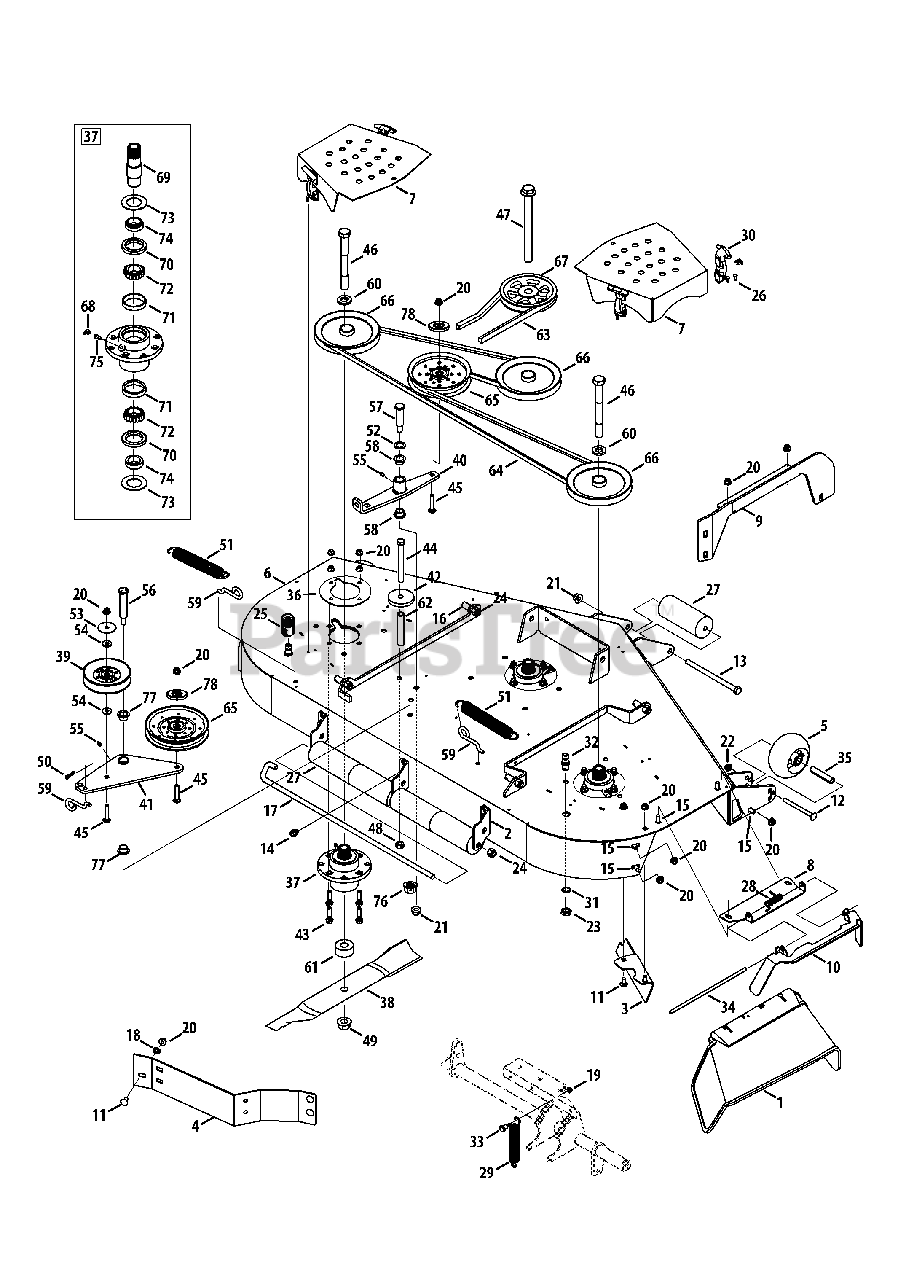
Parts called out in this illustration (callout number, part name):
1	Chute Deflector
4	Baffle, 60" Adjustment
5	Complete Wheel, 5.00 Dia.
6	60" Deck
7	Deck Belt Cover
8	Chute Deflector Bracket
9	Deck Support Plate
10	Chute Extension Bracket
11	Carriage Bolt, 3/8-16 x .750
12	Carriage Bolt, 3/8-16 x 4.00
13	Hex Cap SCrew, 1/2-13 x 7.50
14	Screw, 3/8-16 x .500
15	Carriage Bolt, 3/8-16 x 1.00
16	Pin, 1/2-13 x .625 x 1.2
17	J-Hook w/ Threaded Roller
18	Push Nut, 3/8
19	Nut, 1/4-20, Flangelock
20	Nut, 3/8-16, Flangelock
21	Nut, 1/2-13, Flangelock
22	Nut, 3/8-16, Centerlock
23	Hex Nut, M16-1.5
24	Nut, 1/2-13, Hexlock
25	Water Nozzle Adaptor
26	Pop Rivet, 3/16
27	Front Roller
28	Torsion Spring, 0.639 x 2.16
29	Extension Spring, .969 x 6.180
30	T-Handle Latch Draw
31	Lock Washer, 17 x 23.8 x 1.95
32	Deck Water Nozzle
33	Shoulder Bolt, .437 x .50, 1/4-20
34	Chute Deflector Rod
35	Wheel Spacer
36	Spindle Support Plate
37	Spindle Assembly
38	Hi-Lift Blade, 21.0
39	Idler Pulley
40	Deck Idler Arm
41	Idler Assembly
42	Spacer, .5375 x 2.75 x .375
43	Carriage Bolt, 3/8-16 x 1.5
44	Hex Cap Screw, 1/2-13 x 5.00
45	Carriage Bolt, 3/8-16 x 2.00
46	Hex Cap Screw, 3/4-16 x 7.00
47	Hex Cap Screw, 3/4-16 x 9.00
48	Nut, 1/2-13, Hexlock
49	Nut, 3/4-16, Flangelock
50	Bow Tie Cotter Pin
51	Extension Spring, 1.248 x 8.5
52	Washer, .793 x 1.24 x .06
53	Washer, .406 x 1.92 x .060
54	Washer, .406 x 1.00 x .105
55	Grease Fitting
56	Shoulder Bolt, 1.0 x 3.15, 5/8-18
57	Shoulder Bolt, .750 x 2.23, 1/2-13
58	Flange Bearing, .75 x .52
59	Spring Rod Hook
60	Spacer, .812 x .218
61	Spacer, .760 x 2.00 x .925
62	Spacer, .405 x .75 x 3.875
65	Idler Pulley
66	Spindle Pulley
67	Drive Pulley
68	Grease Fitting, 45 degree, 1/4-28
69	Spindle Shaft
70	Seal, Oil
71	Cup Bearing
72	Cone Bearing
73	Washer, 1.50 x 2.52 x .075
74	Ring, Seal
75	Straight Adapter Fitting
76	Nut, 5/8-18, Flangelock
77	Flange Bearing, 1.00 x .75
78	Pulley Cap
